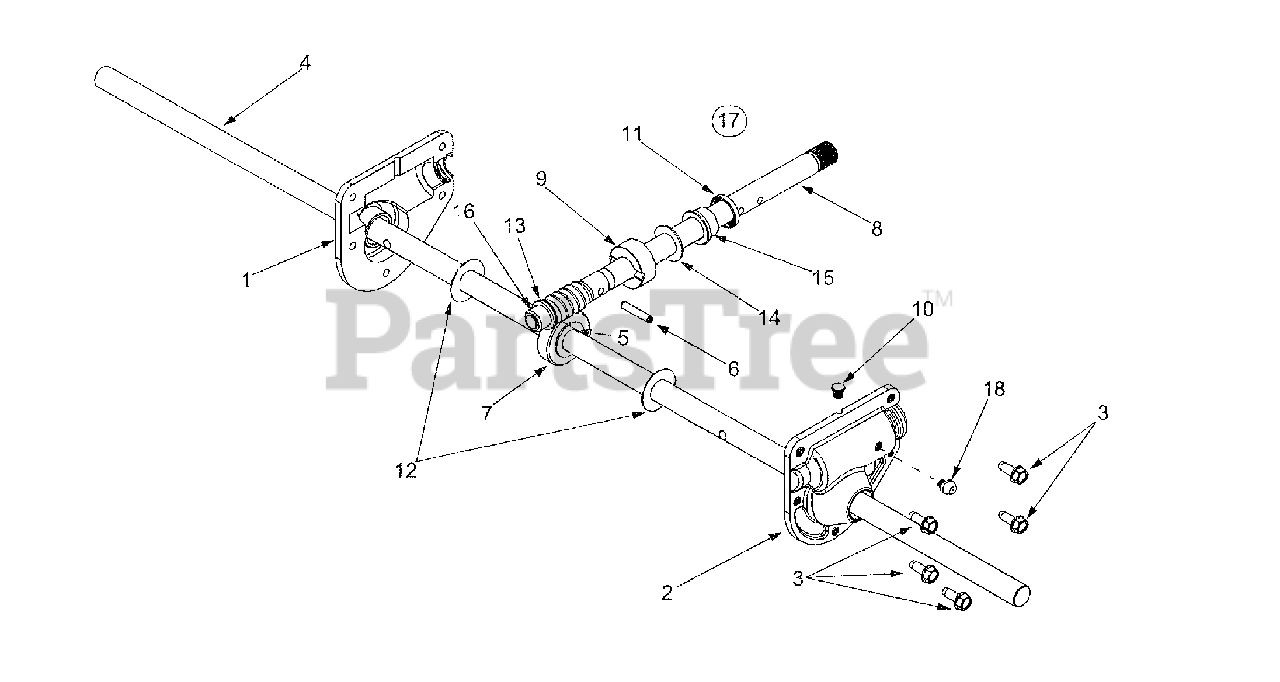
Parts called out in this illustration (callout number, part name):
1	RH Housing
2	LH Housing w/ Fitting
3	Self Tapping Screw, 1/4-20 x .75
4	Spiral Axle 22"
5	Hi-Pro Key, 3/16 x 5/8
6	Spring Spiral Pin, .25 x 1.25
7	Worm Gear, 20-tooth
8	Worm Shaft
9	Thrust Collar
12	Flat Washer, .76 x 1.5 x .030
13	Flat Washer, .508 x 1.0 x .020
14	Flat Washer, .76 x 1.5 x .060
15	Flange Bearing, .75 x 1.0 x .59
16	Flange Bearing, .503 ID x .75 OD
17	Gear Assembly Complete, 22"
18	Grease Fitting, 3/16" Drive
